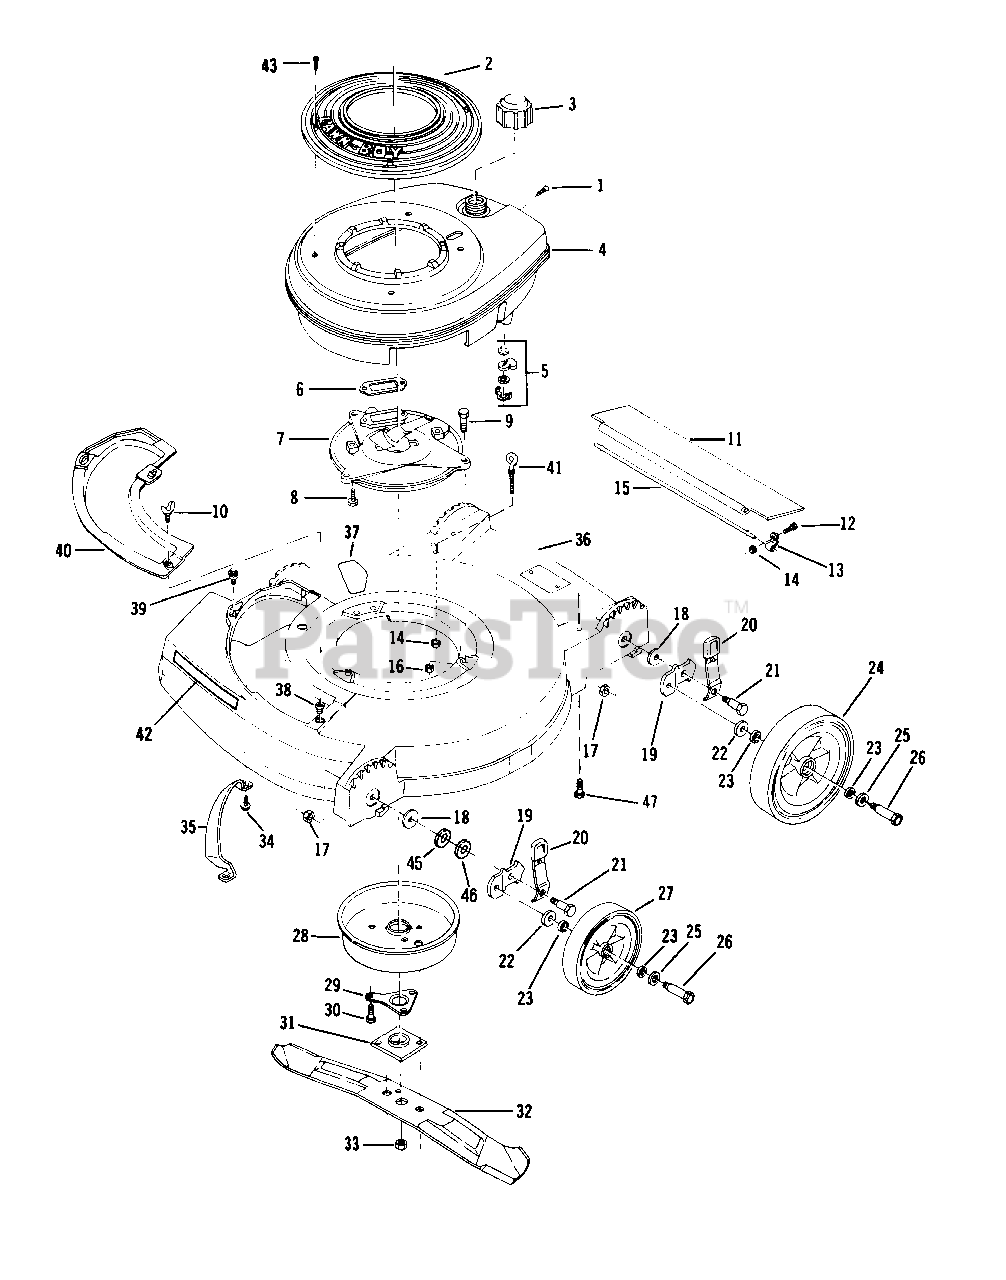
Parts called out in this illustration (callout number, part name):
1	Screw
2	Cover-Shroud
3	Fuel Cap
4	Shroud-Engine
5	Fuel Shut-Off Assembly
6	Gasket-Exhaust
7	Plate-Muffler
8	Screw-Muffler Plate to Block
9	Screw-Muffler Plate to Housing
10	Wing Screw
11	Shield-Trailing
12	Screw
13	Clamp
14	Nut
15	Rod-Trailing Shield
16	Nut-Muffler Plate to Housing
17	Nut-Wheel Height Adjust
18	Washer-Wheel Height Adjust
19	Bracket-Wheel Height Adjust
20	Knob and Spring Assembly
21	Bolt-Shoulder
22	Washer
23	Washer-Felt
24	Wheel-Rear
25	Washer-Wheel Bolt
26	Bolt-Wheel
27	Wheel-Front
28	Muffler Cover Assembly
29	Support-Crankshaft
30	Screw-Muffler to Muffler Plate
31	Collar and Plate Assembly
32	Blade-21"
33	Nut
34	Screw
35	Toe Bar
36	Housing Assembly
37	Decal-Blade Contact Warning
38	Grommet
39	Screw-Plate Mounting
40	Cover Plate
41	Eyebolt
42	Decal-Headliner
43	Screw-Shroud
45	Washer-Shim
46	Washer-Shim
47	Screw-Handle Bracket to Hsg.
